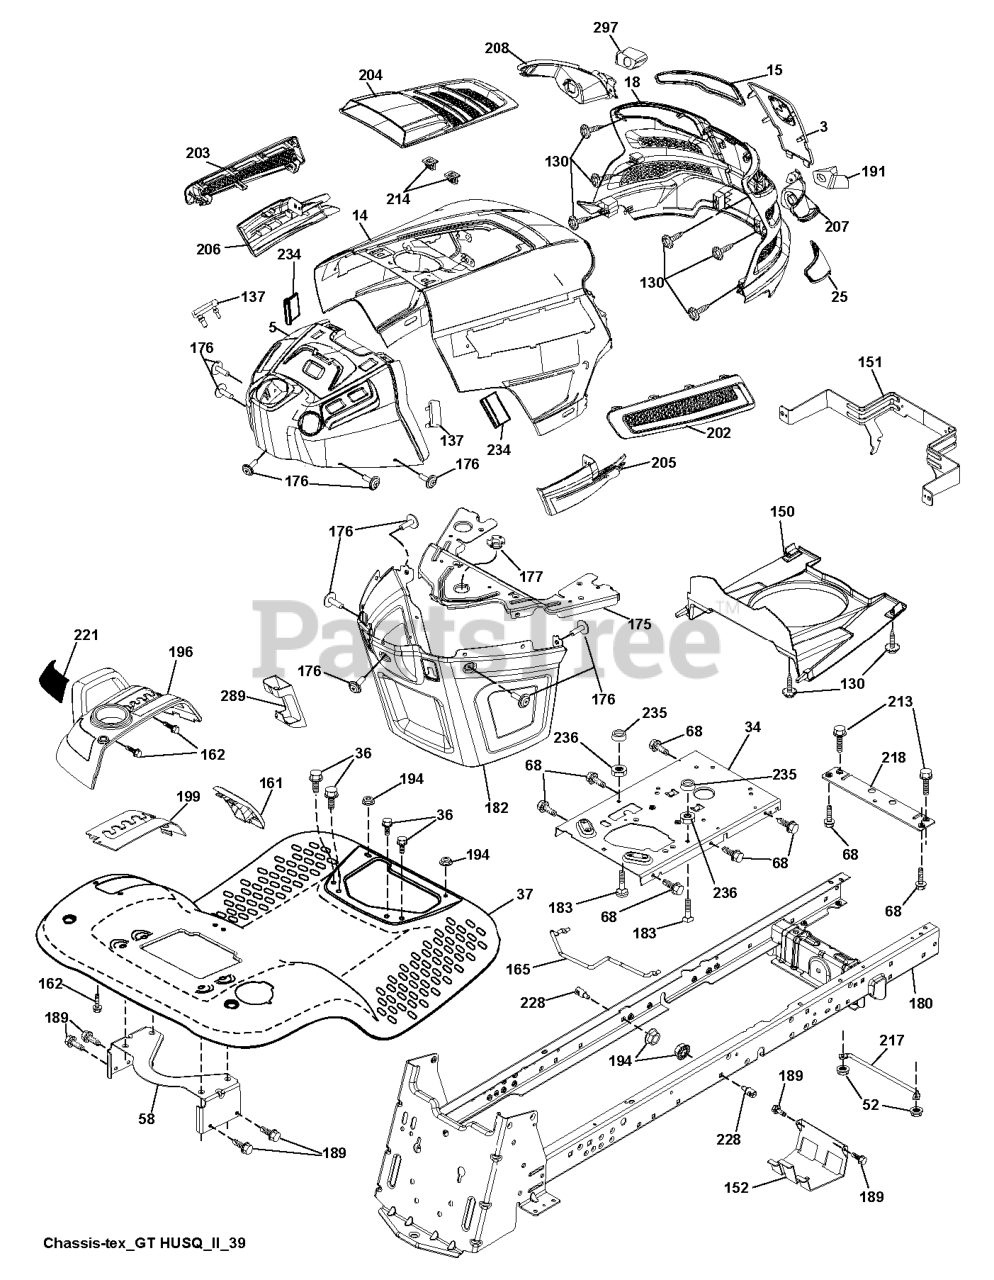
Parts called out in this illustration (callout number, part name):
3	APPLIQUE.SUBASM.GT.HUSQ.II
5	DASH.UPP.GT2.SM.PTO.MCHOKE
14	HOOD.ASM.HUSQVARNA.GT.TEX.422
15	LENS.HEADLIGHT.LH.GTII.2011
18	GRILLE.SUBASM.GT.HUSQ.II
25	LENS.HEADLIGHT.RH.GTII.2011
34	PLATE.ENGINE.WELDED.CHASSIS
36	SCREW 5/16"
37	FENDER.PNT.TX.GT.CH/FW/DL.HUSQ
52	LOCKNUT
58	BRKT.SUPPORT.FNDR/TANK
68	Screw 5/16-18 x 1/2 Hex, Self Tapping 5/16-18 x 1/2
130	SCREW.#10 X 0.750.BOS
137	BUMPER DASH
150	AIR.DUCT.GTV.BLACK
151	BRACKET.PIVOT.HOOD.GT.HUSQ.II
152	SHIELD.BROWNING.W/TEX
161	CONSOLE.WINDOW.FUEL.HUSQ.GT
162	SCREW.HI-LO.CONSOLE
165	SUPPORT.TANK.REAR.W/TEX
175	PLATE.CROSSMEMBER.HUSQ
176	SCREW.#10-24X5/8.RN.QU
177	BUSHING, STEERING
180	CHASSIS.GT.SLOPED.DRAWBAR.
182	DASH.LOWER.COMMON.12V.ADAPTOR
183	BOLT.5/16-18X1-1/4 FULL.THREAD
189	SCREW
191	INSERT.REFLECTIVE.RH.HUSQ.GTII
194	NUT LOCK HEX FLANGE 5/16-18
196	SUBASM.CONSOLE.HUSQ.GT.DECKLFT
199	PLATE.DECK.LIFT.HUSQVARNA.GT
202	VENT.SIDE.RH.GT.HUSQ.II.
203	VENT.SIDE.LH.GT.HUSQ.II.498
204	VENT.TOP.HUSQ.GT2
205	SIDE.TRIM.RH.GT.HUSQ.II
206	SIDE.TRIM.LH.GT.HUSQ.II.GRAY
207	BEZEL LIGHT.RH.GT.II.MYLAR
208	BEZEL LIGHT.LH.GT.II.MYLAR
213	BOLT
214	CLIP.RETAINER.TINNER.
217	ROD.PIVOT.HOOD
218	X-PIECE.HOOD.STOP.NON/
221	REFLECTOR.LH.TEX GT HU
228	STUD.FASTNER.W/ANTI-ROTATE
234	BUMPER.HOOD.TEX.HUSQVARNA
235	SPACER FENDER
236	NUT.CENTERLOCK.5/16-
289	PLUG.N/CRUISE.COMMON.YT/GT.BLK
297	INSERT.REFLECTIVE.LH.HUSQ.GTII
